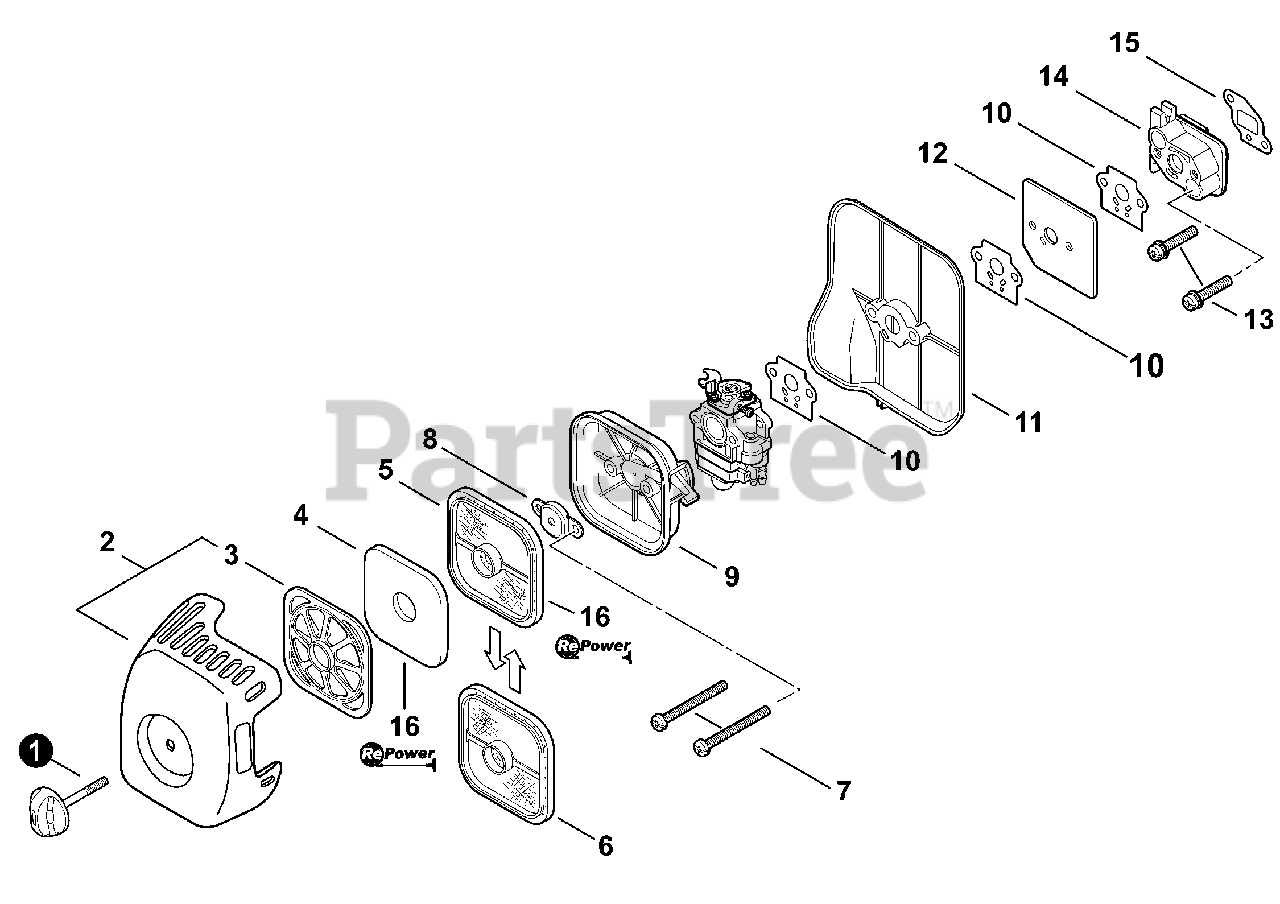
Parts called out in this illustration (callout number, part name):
1	THUMBSCREW
2	AIR CLEANER COVER KIT
3	RETAINER, PRE-FILTER
4	PRE-FILTER - FOAM
5	FILTER, AIR - DOUBLE LAYER
6	FILTER, AIR - SINGLE LAYER
7	SCREW 5×70
8	PLATE, PREVENT
9	CASE, AIR CLEANER - BLACK
10	GASKET, INTAKE
11	PLATE, INSULATOR
12	PLATE, INSULATOR
13	SCREW - 5×30
14	INSULATOR
15	GASKET, INTAKE
16	TUNE-UP KIT - REPOWER
